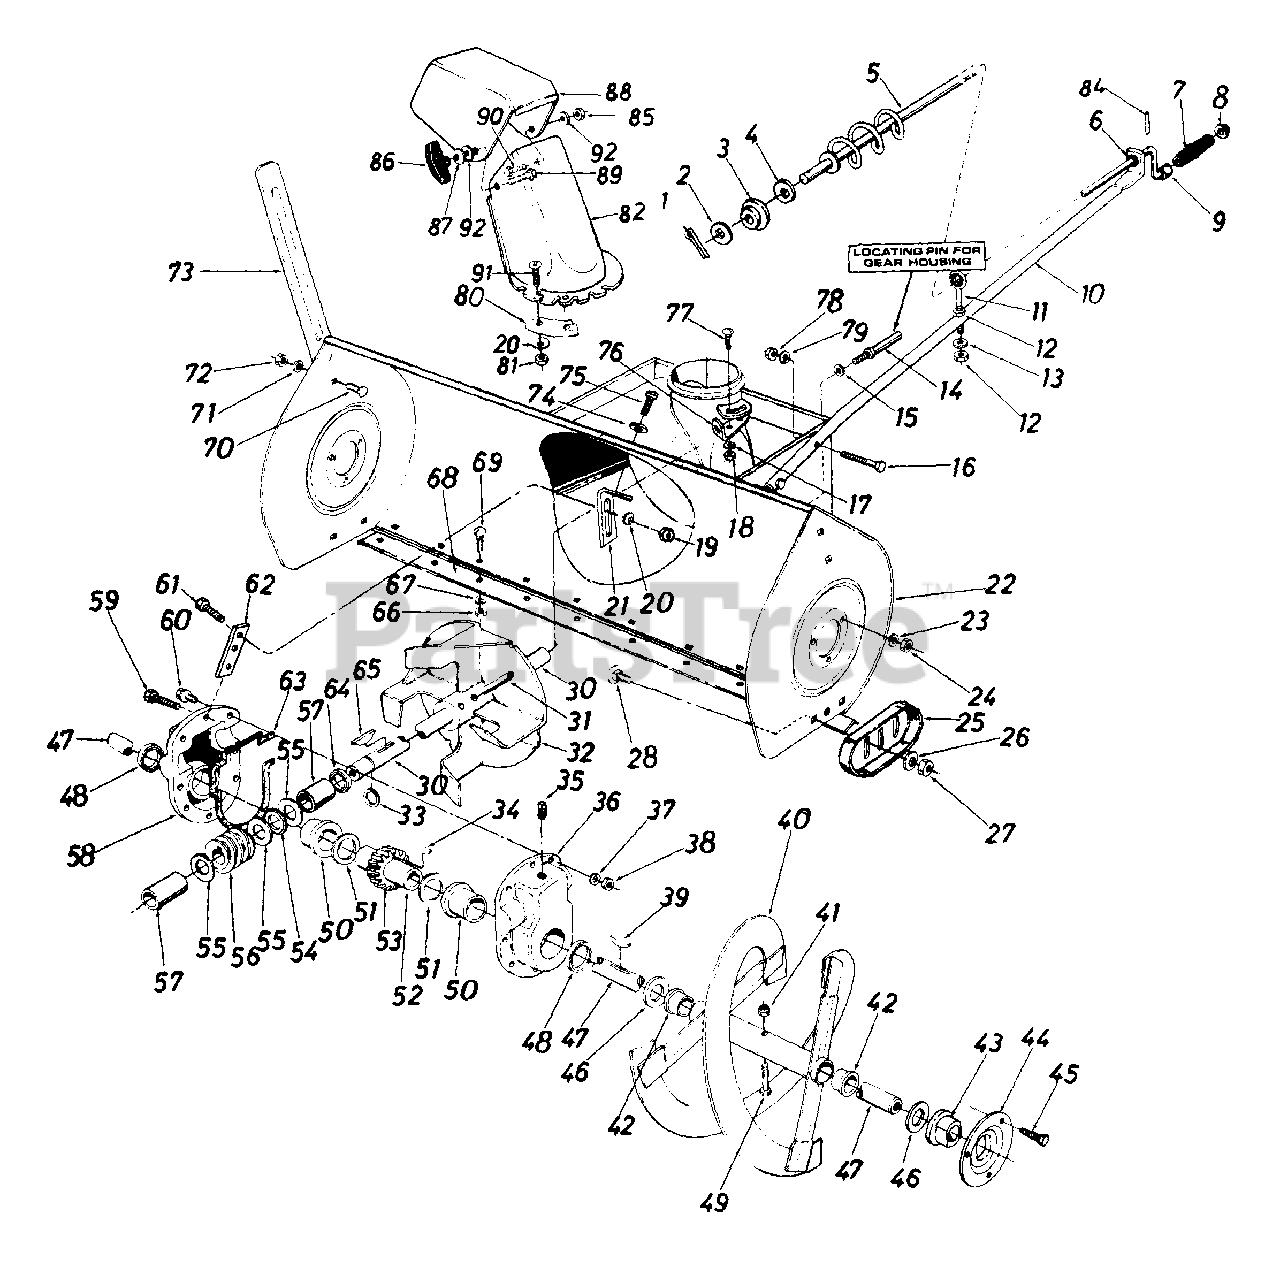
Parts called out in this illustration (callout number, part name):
2	Fl-Wash. .39" I.D. x .62" O.D.
3	Plastic Bushing
4	Fl-Wash. .385" I.D. x .62" O.D.
5	Chute Crank Ass'y.
6	Plastic Bushing
7	Knob (Black)
8	Push Nut 3/8" Rod
9	Spacer .385" I.D. x .50" O.D.
10	Chute Crank Support Tubing
12	Hex Nut 5/16-18 Thd.
13	Bell-Wash. .345" I.D. x .88" O.D.
14	Stud 3/8-16 x 2.75" Lg.
15	Bell-Wash. .400" I.D. x .88" O.D.
16	Hex Bolt 3/8-24 x 1.25" Lg.
17	Bell-Wash. .345" I.D. x .88" O.D.
18	Hex Nut 5/16-18 Thd.
19	Hex Nut 1/4-28 Thd.
20	Bell-Wash. .265" I.D. x .75" O.D.
22	45" Snow Blower Housing Ass'y.
23	L-Wash. 5/16" I.D.
24	Hex Nut 5/16-18 Thd.
25	Slide Shoe
26	Bell-Wash. .400" I.D. x .88" O.D.
27	Hex Jam Nut 3/8-16 Thd.
28	Carriage Bolt 3/8-16 x .62" Lg.
30	Blower Axle .875" Dia. x 14.75" Lg.
31	Spring Pin Spir. 5/16" Dia. x 1.75" Lg.
34	#91 Woodr-Key 1/4 x 3/4" Dia. (Hdn)
36	Comp. Gear Hsg. Half - L.H.
37	Spr.-Wash. .32" I.D. x .62" O.D.
38	Hex Ins. L-Nut 5/16-18 Thd.
39	#91 Woodr-Key 1/4 x 3/4" Dia. (Hdn)
41	Hex Ins. L-Nut 5/16-18 Thd.
42	Plastic Bushing
43	Flange Brg. w/flats 1" I.D.
44	Bearing Housing
45	Hex Sems Bolt 5/16-18 x .75" Lg.
46	Fl-Wash. 1.00" l.D. x 1.75" O.D.
48	Flange Bearing 1.503" I.D.
49	Shear Bolt 5/16-18 x 1.75" Lg.
50	Oil Seal 1.50" I.D.
51	Fl-Wash. 1.50" I.D. x 2.00" O.D.
52	Worm Gear Shaft
53	Double Threaded Worm Gear - L.H.
54	Thrust Brg.-.88" I.D. x 1.44" O.D.
55	Fl-Wash. .88" I.D. x 1.4" O.D.
56	Double Threaded Worm - L.H.
57	Sleeve
58	Complete Gear Hsg. Half - R.H.
59	Hex Bolt 5/16-18 x 1.25" Lg.
60	Hex Bolt 5/16-18 x 1.0" Lg. (Gr. 5)
61	Hex Bolt 1/4-28 x .75" Lg.
62	Gear Housing Support Plate
63	Rubber Gasket
64	Oil Seal -.875" I.D.
65	#9 Hi-Pro Key 3/16 x 3/4" Dia. (HT)
66	Hex Nut 5/16-18 Thd.
67	L-Wash. 5/16" I.D.
69	Carriage Bolt 5/16-18 x 1.00" Lg.
70	Carriage Bolt 5/16-18 x .62" Lg.
71	L-Wash. 5/16" I.D."
72	Hex Nut 5/16-18 Thd.
73	Guide Blade
74	Bell-Wash. .345" I.D. x .88" O.D.
75	Hex Wash. Hd. AB-Tap Scr. 5/16 x .75" Lg.
77	Carriage Bolt 5/16-18 x .75" Lg.
78	Hex Ins. L-Nut 3/8-24 Thd.
79	L-Wash. 3/8" I.D.
80	Chute Flange Keeper
81	Hex Nut 1/4-20 Thd.
82	Chute Ass'y. w/Chute Guard
84	Bell-Wash. .345" I.D. x .88" O.D.
85	Hex Cent. L-Nut 5/16-18 Thd.
86	Knob Handle
87	Bell-Wash. .345" I.D. x .88" O.D.
88	Top Chute Ass'y.
89	Carriage Bolt 5/16-18 x 1.00" Lg.
90	Carriage Bolt 5/26-18 x .62" Lg.
91	Truss Mach. Scr. 1/4-20 x .75"
92	Roll Pin.12 Dia. x .63"
